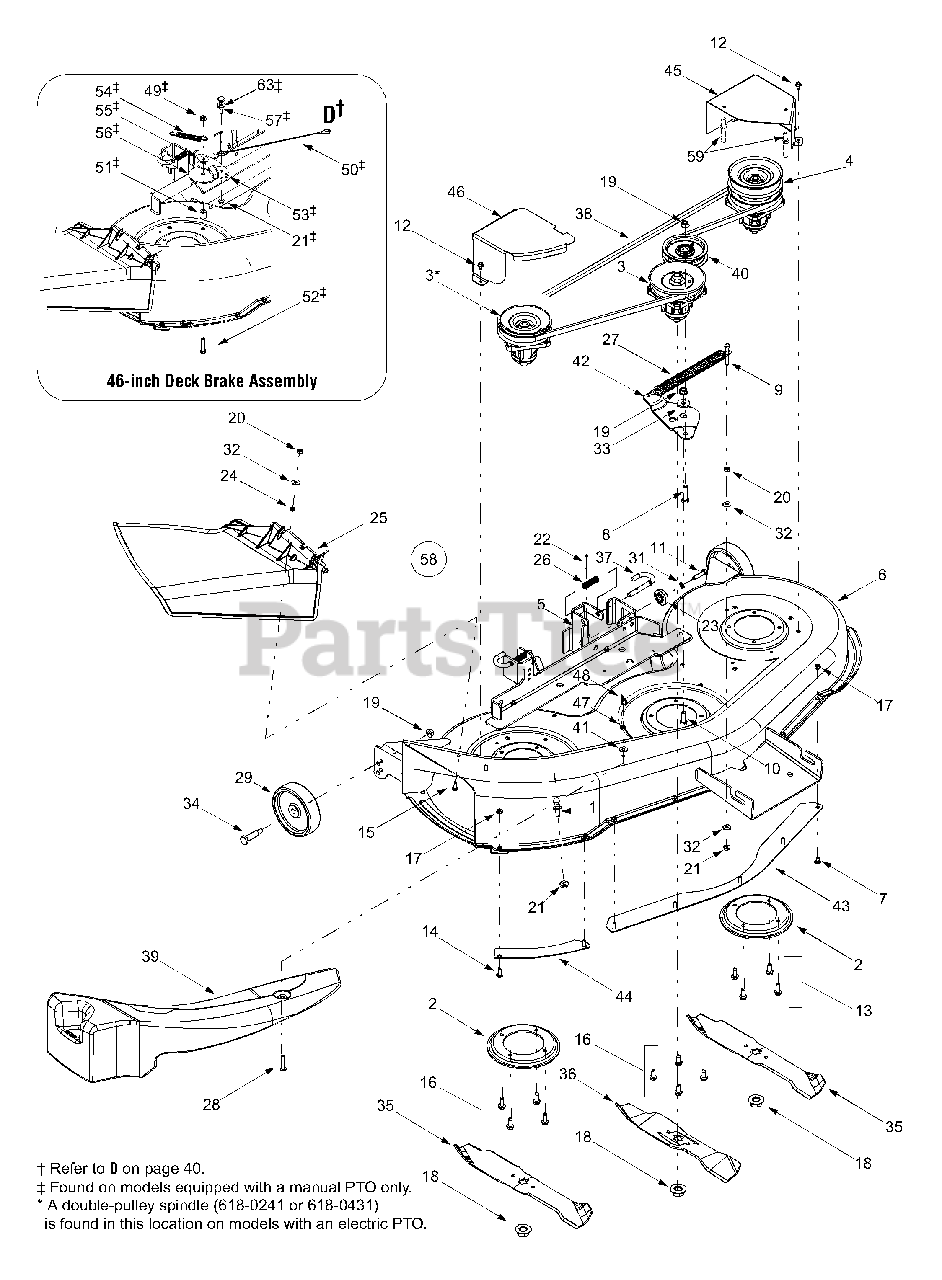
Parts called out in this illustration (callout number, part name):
1	Grass Catcher Pin
4	Double Pulley Spindle Assembly
8	Hex Cap Screw, 3/8-16 x 1.5
9	Hex Cap Screw, 1/4-20 x 2.0
10	Hex Cap Screw, 3/8-16 x 1.0
11	Hex Cap Screw, 5/8-18 x 1.25
12	Self-tapping Screw,1/4-20 x.5
13	Self-tapping Screw,15/16-18 x.875
14	Hex Screw, 1/4-20 x.75
15	Hex Cap Screw, 1/4-20 x.62
16	Self-tapping Screw, 5/16-18 x.75
17	Hex Sems Nut, 1/4-20
18	Hex Flange Nut, 5/8-18
19	Flange Lock Nut, 3/8-16
20	Hex Nut, 1/4-20
21	Hex Flange Lock Nut, 1/4-20
22	Cotter Pin, 1/8 x 1.25
23	Deck Adjustment Gear
24	Push Nut.25 x.5
25	Side Discharge Chute Assembly
26	Compression Spring,.406 x.531 x 1.75
27	Extension Spring,.91 x 7.3
28	Screw, 1/4-20 x 1.5
29	Deck Wheel, 5 x 1.38
31	Lock Washer, 5/16
32	Bell Washer,.265 x.75 x.062
33	Shoulder Spacer,.625 x 1.16
34	Shoulder Screw
35	Three-in-one Blade, Star Center, 16.28"
36	Three-in-one Blade, Star Center, 14.88"
37	Deck Release Pin
38	Deck Belt, Poly
39	Mulch Plug
40	Idler Pulley, 3.5
41	Flat Washer,.28 x.74 x.063
47	Hex Nut, 1/4-20
48	Wing Nut, 1/4-20
49	Hex Nut, 5/16-18
50	Bracket Cable, 12"
51	Spacer,.385 x.625 x.70
52	Hex Cap Screw, 5/16-18 x 1.5
53	Deck Brake Assembly
54	Extension Spring,.5 x 3.97
55	Shoulder Spacer
56	Flat Washer,.34 x 2.25 x.1
57	Pin, 1/4-20
63	Flat Washer,.385 x.62 x.06
